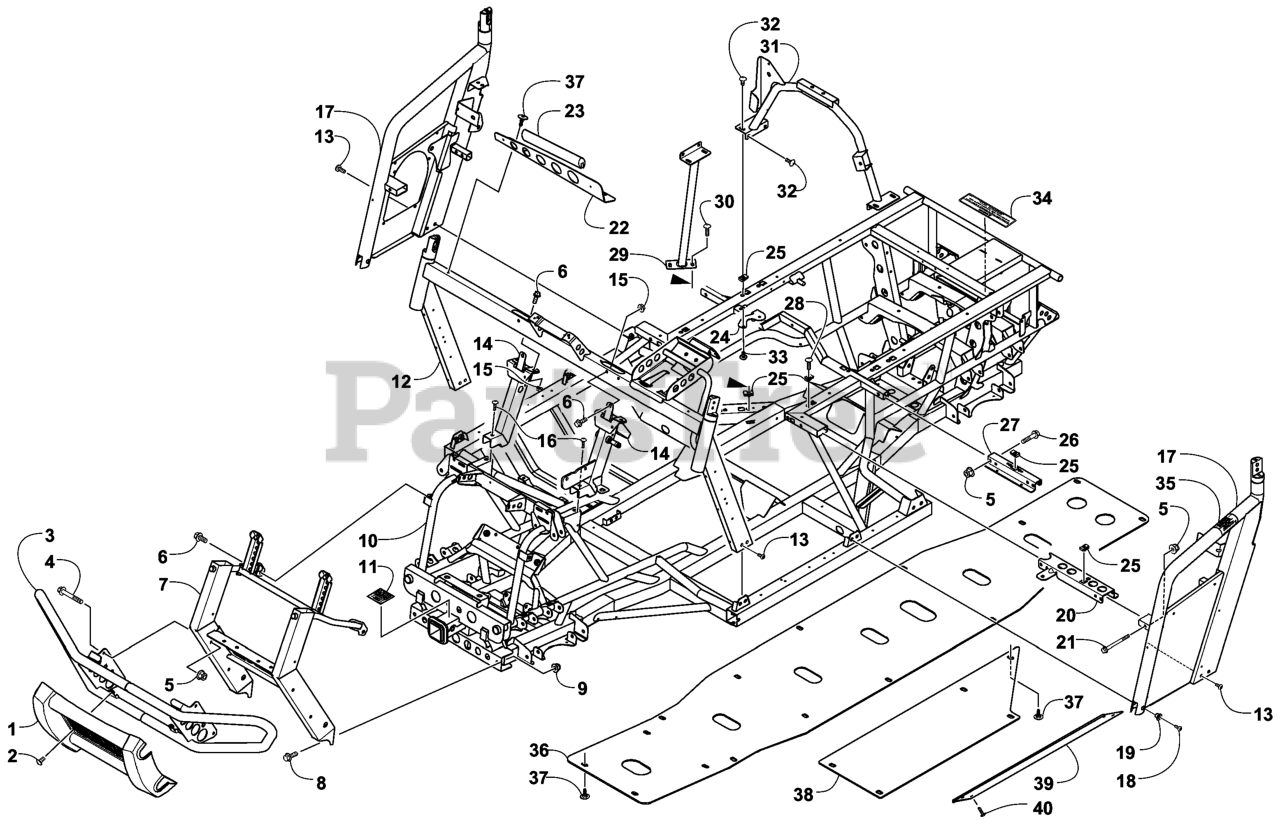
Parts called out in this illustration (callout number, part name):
1	FASCIA-BUMPER, FRONT
2	SCREW-TSPRH
3	BUMPER-PUSH
4	SCREW-HFH
5	NUT-HHF, LOCK, (NI)
6	SCREW-HFH
8	SCREW-HFH
9	NUT-HHF, LOCK (NI)
11	DECAL-WARNING, TOWING
12	SUPPORT-STEERING
13	SCREW-TSPRH
14	BRACKET-SUPPORT, STEERING
15	NUT-HHF
17	SUPPORT-ARM, RH
17	SUPPORT-ARM, LH
18	SCREW-TSTH
19	SPACER-STEEL
20	BRACKET-SEAT SUPPORT,FRON
21	SCREW-HFH
22	BRACKET-SUPPORT, HOOD (RH
22	BRACKET-SUPPORT, HOOD (LH
23	TRIM-EDGE, RUBBER
24	BRACKET-AIR INTAKE
25	CLIP-U NUT
26	SCREW-HFH
27	BRACKET-SEAT SUPPORT,REAR
28	SCREW-TSPRH
29	TUBE-SUPPRT
30	SCREW-TSPRH
31	SUPPORT-REAR CANOPY
32	SCREW-TSPRH
34	DECAL-WARNING, TOWING
35	DECAL-WARNING, ROPS
36	SKIDPLATE-MAIN
37	SCREW-SELF TAP
38	SKIDPLATE-SIDE
39	PLATE-SKID, SIDE
40	SCREW,MAC-TSBWH
